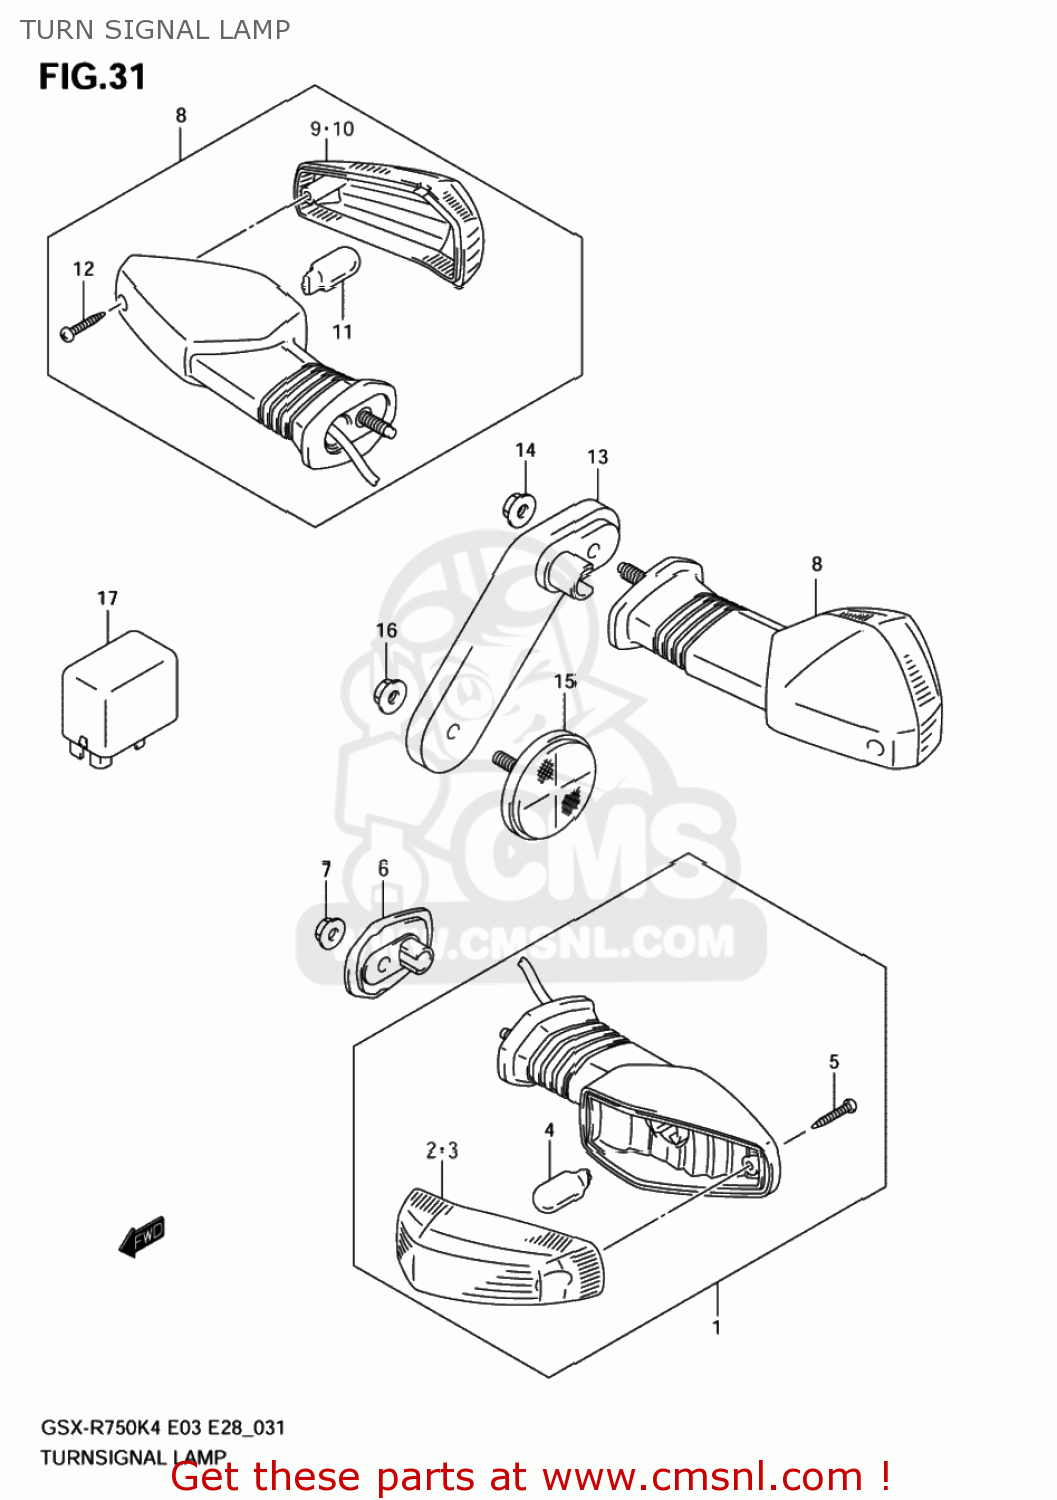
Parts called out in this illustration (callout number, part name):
1	LAMP ASSY,FR TURN SIGNAL,R
2	LENS
3	LENS
4	BULB(12V18W)
5	SCREW
6	PLATE,FR TURNSIGNAL
7	NUT
8	LAMP ASSY,RR TURNSIGNAL,R
9	LENS
10	LENS
11	BULB(12V18W)
12	SCREW
13	PLATE,RR TURN SIGNAL,R
14	NUT
15	REFLECTOR ASSY,RR SIDE
16	NUT
17	RELAY ASSY,TURNSIGNAL
